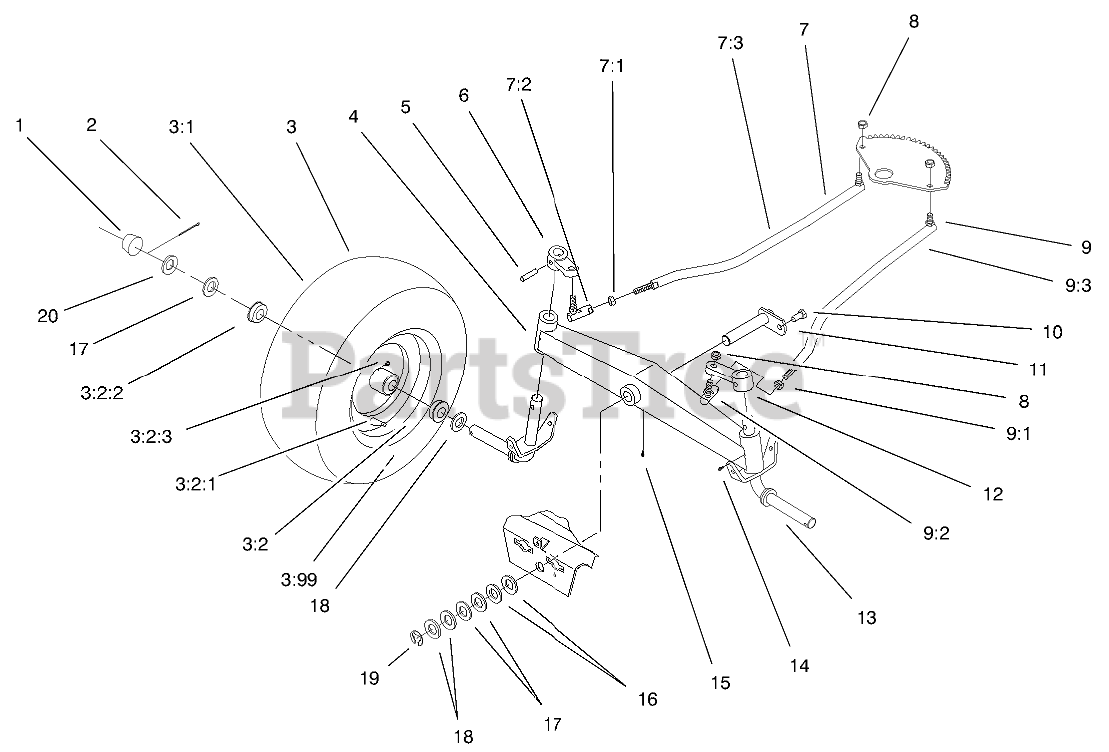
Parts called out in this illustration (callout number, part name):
1	CAP-HUB
2	PIN-COTTER
3	Wheel&tire ASM,Front
3:2	Wheel ASM
3:2:1	VALVE
3:2:2	BEARING-WHEEL
3:2:3	ZERK-GREASE
3:99	TUBE-INNER
4	AXLE-FRONT
6	Arm-Front Spindle
7	LINKAGE-STEERING, RH
7:1	NUT-JAM
7:2	BALL-JOINT
7:3	Ball Link ASM
9	LINKAGE-STEERING, LH
9:1	NUT-JAM
9:2	BALL-JOINT
9:3	Ball Link ASM
10	SCREW-HWH, TAPTITE
11	PIN-AXLE
12	Arm-Front Spindle
13	SPINDLE
14	FITTING-GREASE
15	FITTING-LUBE, 45 DEG
16	Washer
17	WASHER
18	WASHER-SHIM
19	E-RING
20	WASHER-PLAIN
